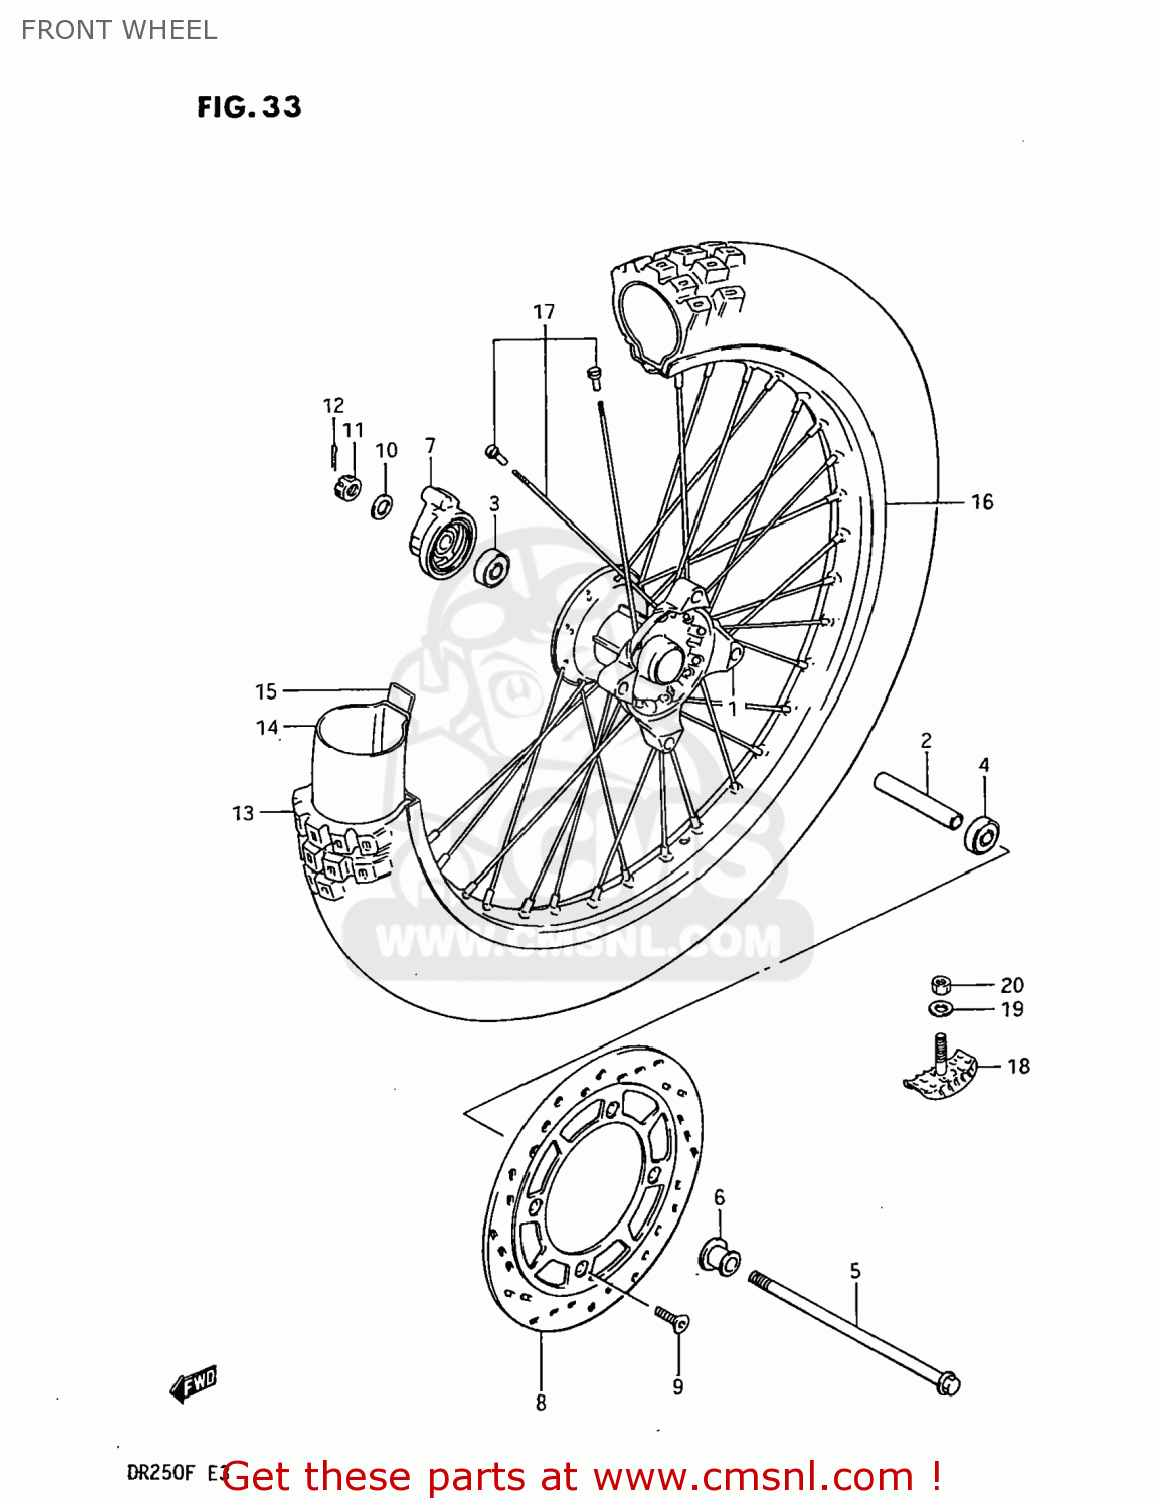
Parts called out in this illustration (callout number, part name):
1	HUB,FRONT
2	SPACER (12.6X19X60.5)
3	BEARING
4	BEARING, RH
5	AXLE,FRONT
6	SPACER,FRONT AXLE,RIGHT
7	BOX ASSY,SPEEDOMETER GEAR
8	DISC,FR BRAKE
9	BOLT,BRAKE DISC
10	WASHER
11	NUT, REAR AXLE
12	COTTER PIN
13	TIRE,FRONT
14	TUBE
15	PROTECTOR,WHEEL,INNER
16	RIM,FRONT WHEEL
17	SPOKE SET,FRONT
18	STOPPER,BEAD
19	WASHER
20	NUT
